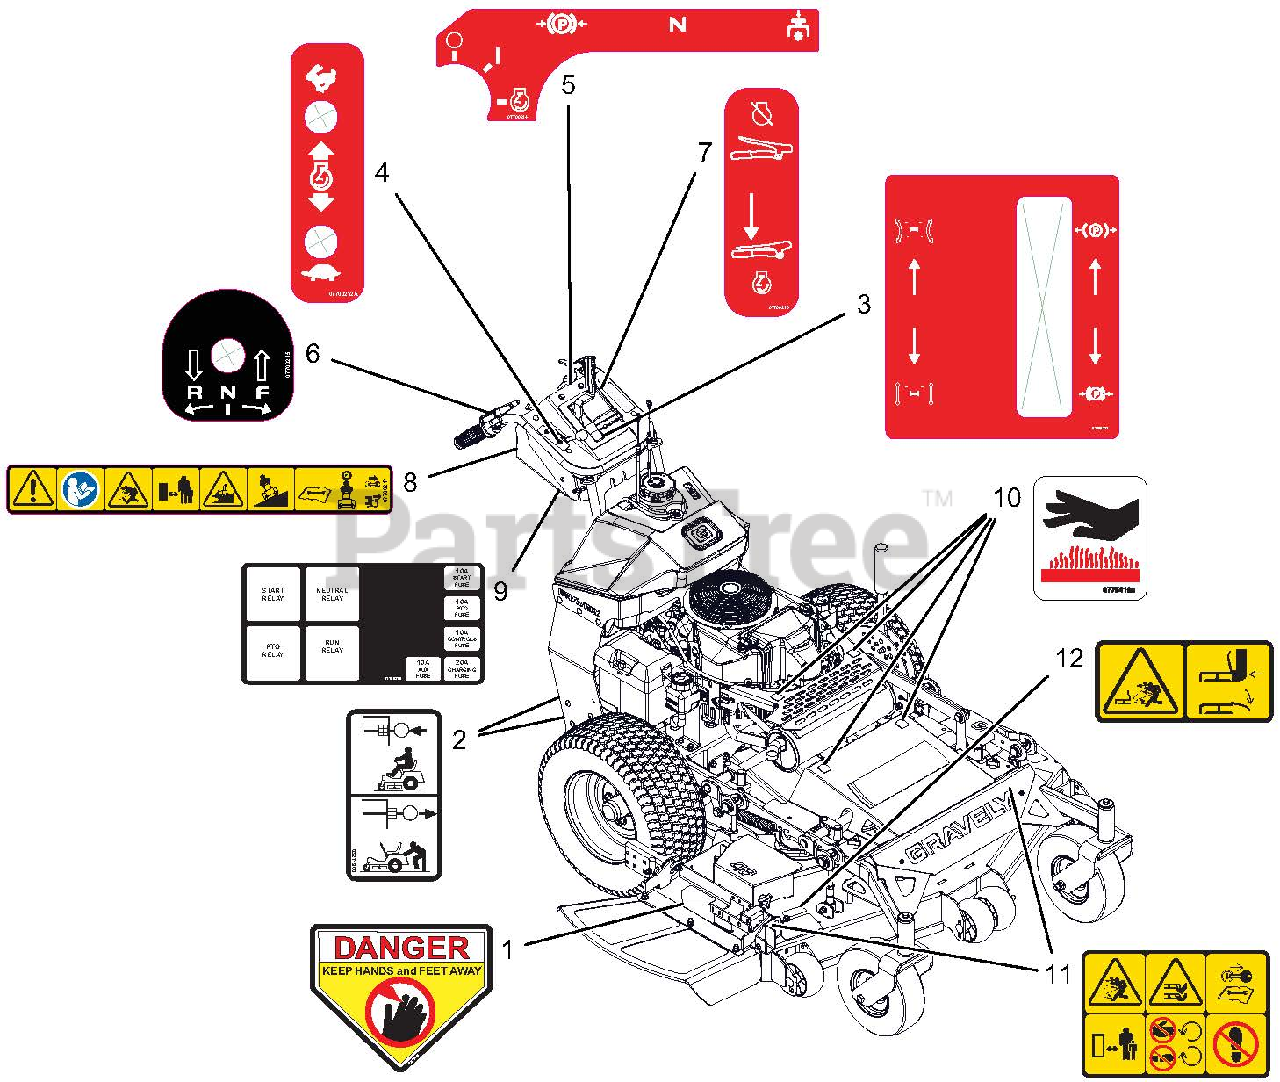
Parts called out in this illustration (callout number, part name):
1	DECAL, DANGER
2	DECAL, TRANSMISSION DISCONNECT
3	DECAL, PARKING BRAKE/STEERING
4	DECAL, THROTTLE
5	DECAL, DASH PANEL PRO-WALK
6	DECAL, DRIVE CONTROLS
7	DECAL, OPERATOR CONTROLS
8	DECAL, SAFETY
9	DECAL, PROWALK FUSE BLOCK
10	DECAL, HOT SURFACE
11	DECAL, SAFETY - MOWER DECK
12	DECAL, SAFETY - DECK GUARDING
